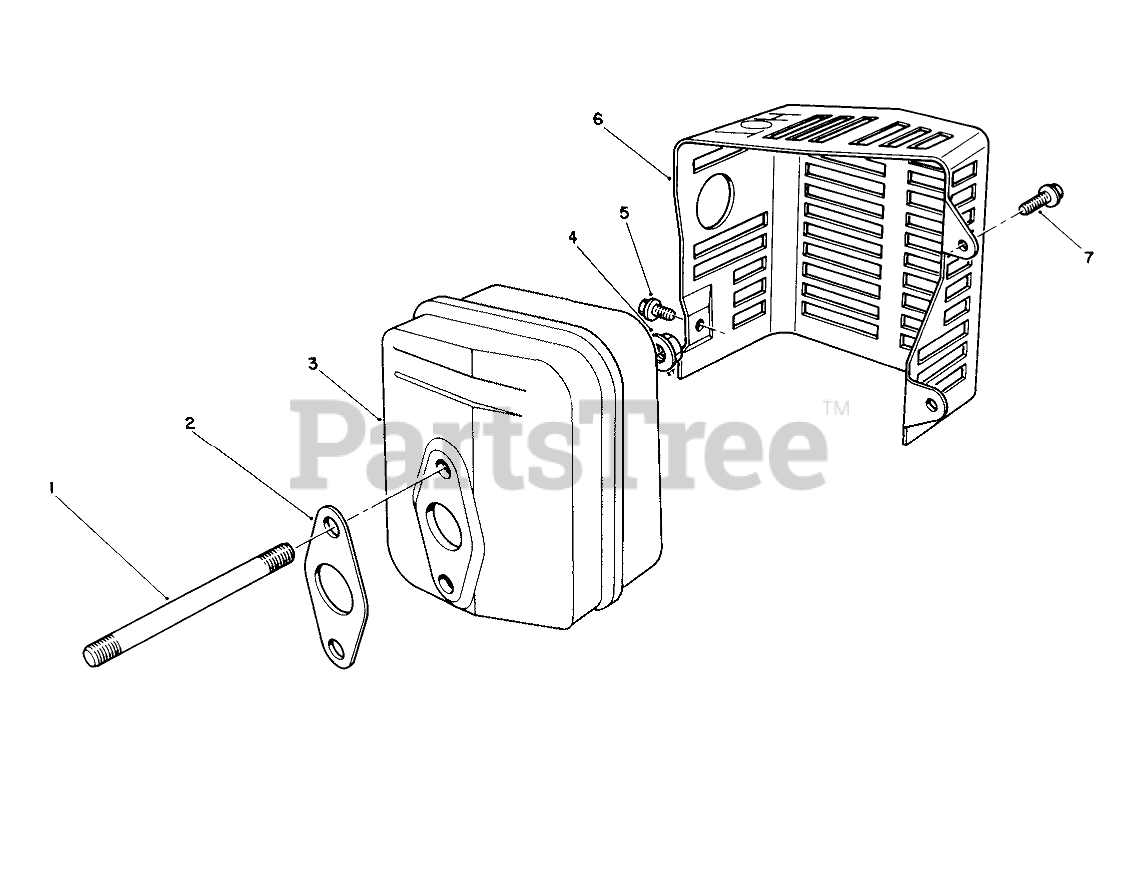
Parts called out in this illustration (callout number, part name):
2	GASKET
3	MUFFLER
5	SCREW
6	COVER
